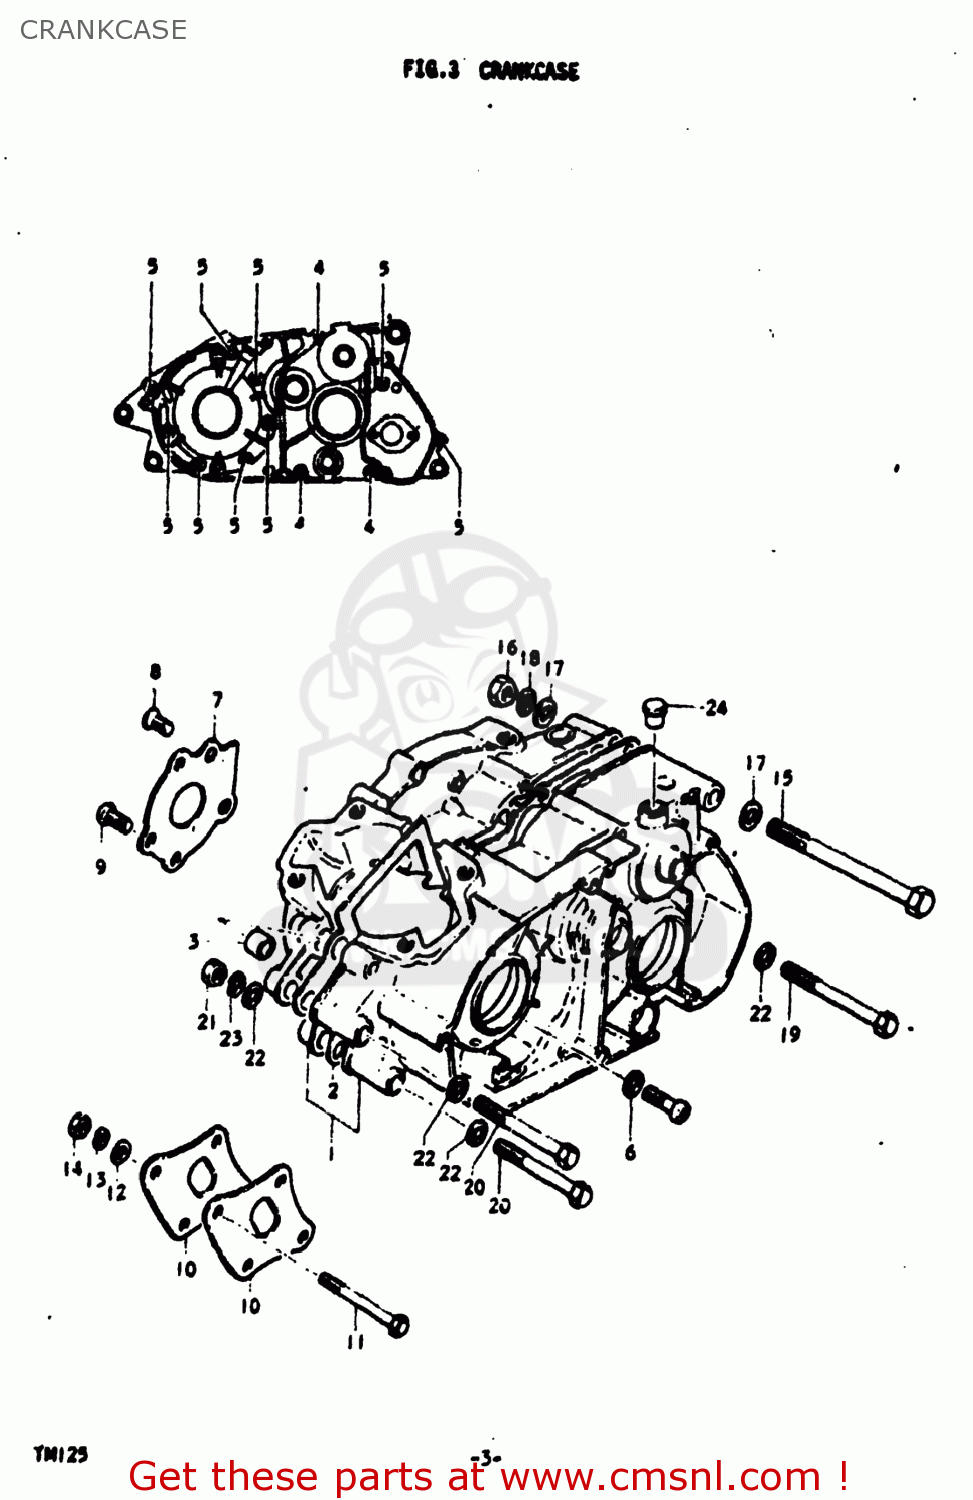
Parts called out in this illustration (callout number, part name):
1	CRANKCASE SET
2	GASKET,CRANKCASE (MCA)
3	PIN
4	SCREW
5	SCREW (6X45)
6	WASHER 6MM
7	PLATE,OIL RESERVOIR
8	SCREW
9	SCREW
10	PLATE,ENGINE MOUNTING
11	BOLT
12	WASHER
13	LOCK WASHER
14	NUT
15	BOLT
16	NUT
17	WASHER
18	LOCK WASHER
19	HEXAGON BOLT 8X80
20	BOLT
21	NUT
22	WASHER
23	LOCK WASHER
24	CAP(OD:14)
